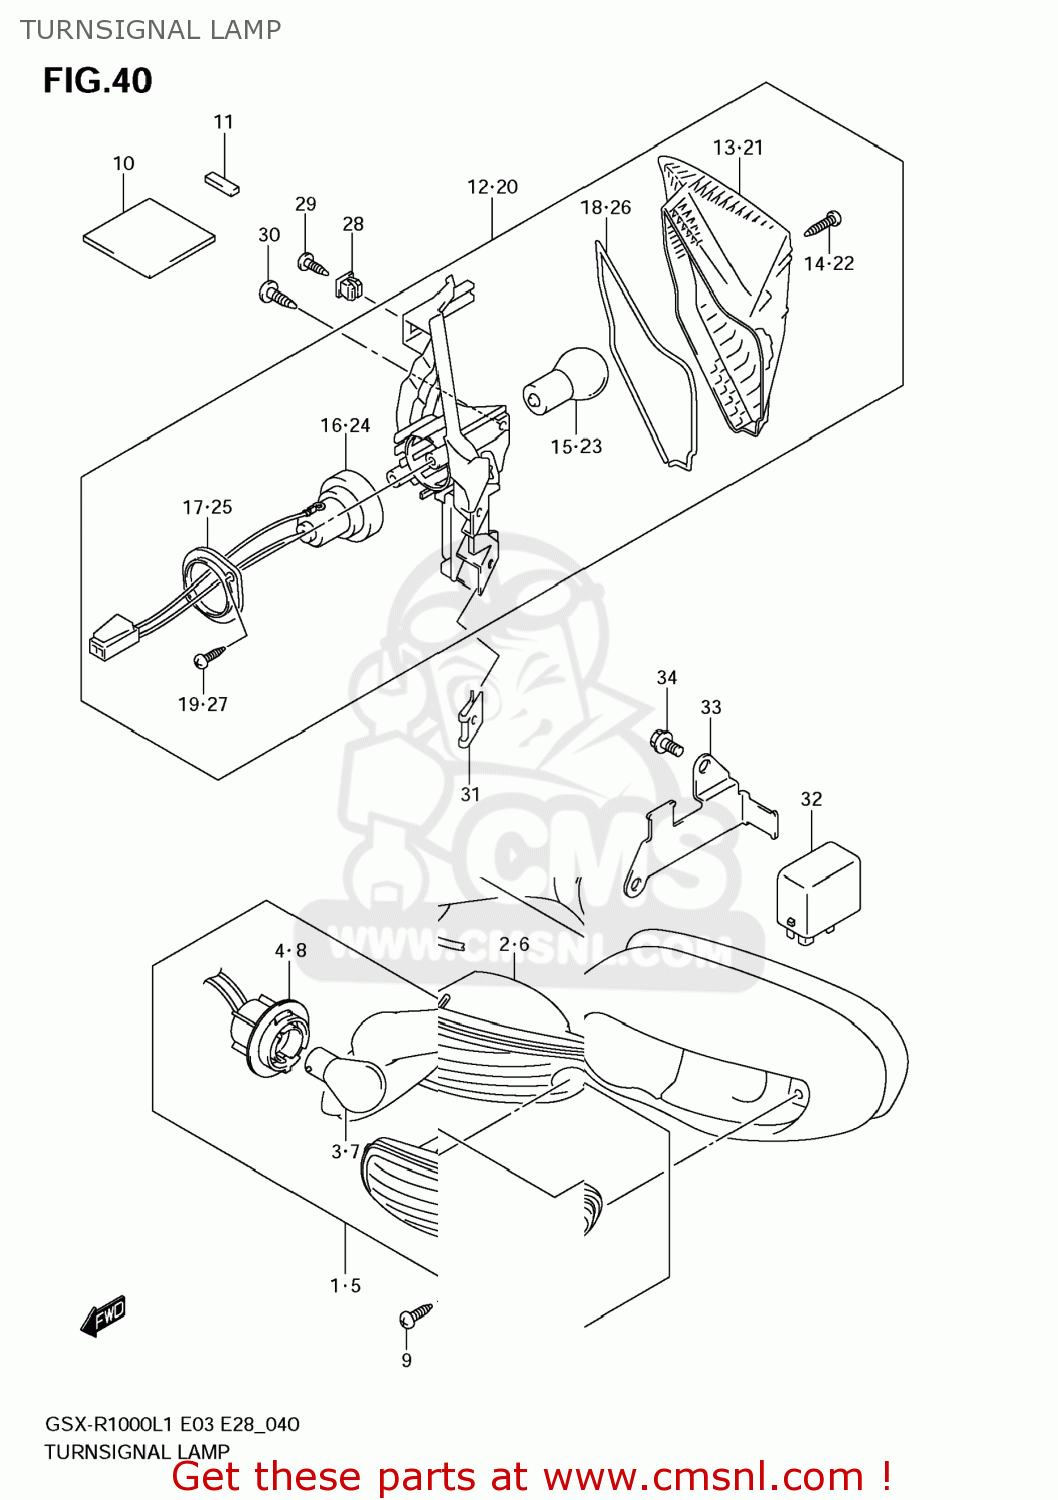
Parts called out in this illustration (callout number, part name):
1	LAMP ASSY,FR TURN SIGNAL,R
2	LAMP UNIT,R
3	SOCKET,R
4	BULB(12V21W,AMBER)
5	LAMP ASSY,FR TURN SIGNAL,L
6	LAMP UNIT,L
7	SOCKET,L
8	BULB(12V21W,AMBER)
9	SCREW(4X20)
10	CUSHION(40X20X5)
11	TAPE,FR TURNSIGNAL
12	LAMP ASSY,RR TURNSIGNAL,R
13	LENS,R
14	SCREW
15	BULB(12V21W,AMBER)
16	SOCKET & CORD,R
17	PLATE,RR COMBINATION
18	GASKET (NAS)
19	SCREW
20	LAMP ASSY,RR TURNSIGNAL,L
21	LENS,L
22	SCREW
23	BULB(12V21W,AMBER)
24	SOCKET & CORD,L
25	PLATE,RR COMBINATION
26	GASKET (NAS)
27	SCREW
28	NUT
29	SCREW
30	SCREW
31	NUT
32	RELAY ASSY,TURNSIGNAL LAMP
33	BRACKET,RELAY
34	BOLT
